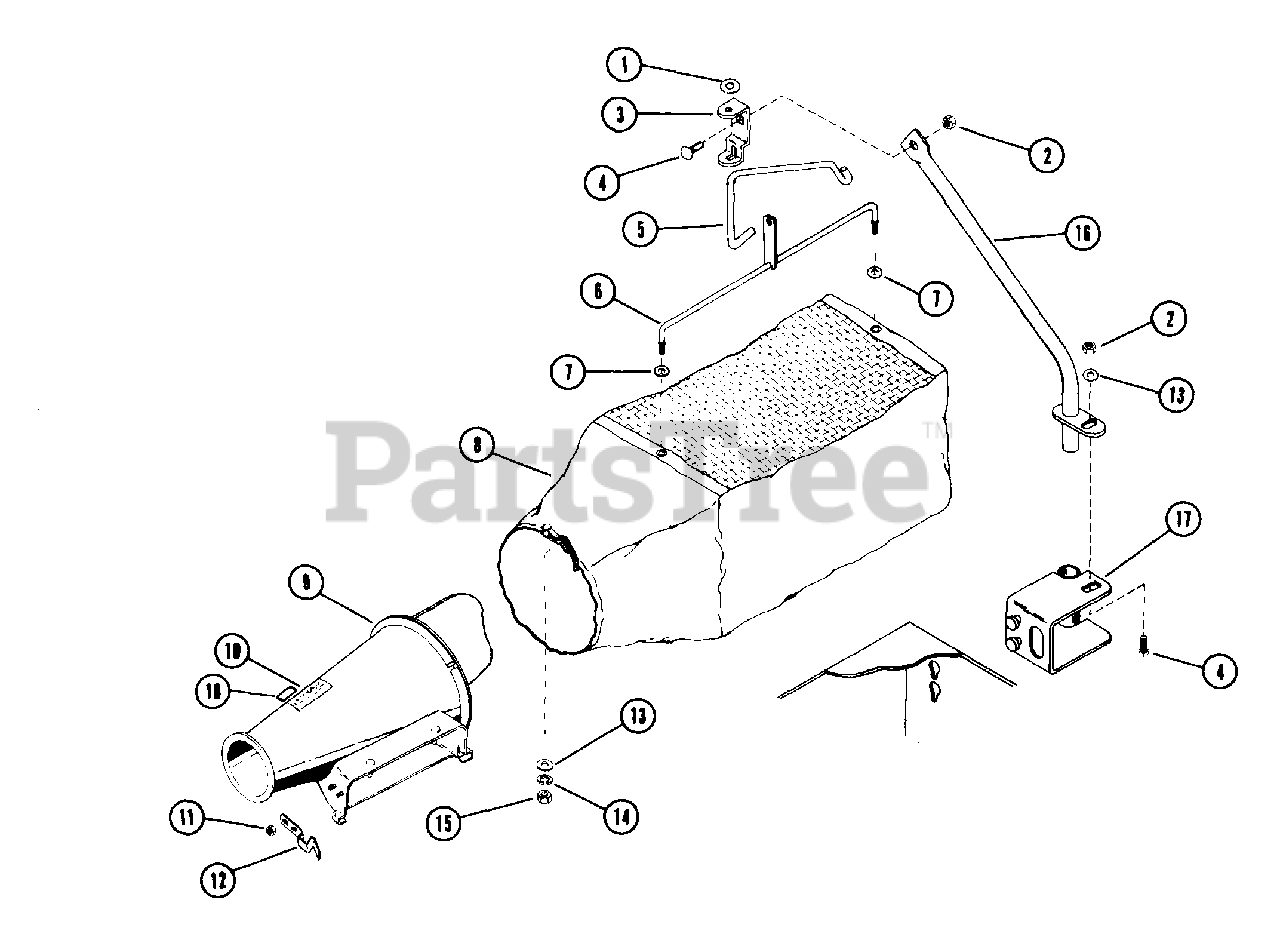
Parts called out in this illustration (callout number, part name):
1	WSHR-FL-STL .323X.625X.062 PL
2	NUT-LK-CTR .375-16 GR A PL
3	STABILIZER BRACKET
4	BLT-RDHDSQNK .38-16X.75 SHT PL
5	STABILIZER ROD
6	CROSS BAR
7	WSHR-FL-STL .38X.875X.083 PL
8	GRASS CATCHER BAG
9	CONE ASSEMBLY
10	CAUTION LABEL
11	NUT-LK-FLG .250-20 PL
12	SPRING, FLAT
13	WSHR-FL-STL.406X.812X.065PL
14	WSHR-LK .375X.115 HVY PL
15	NUT-HEX .375-16
16	SUPPORT BAR
17	SUPPORT BAR BRACKET
18	PATENTS PENDING LABEL
